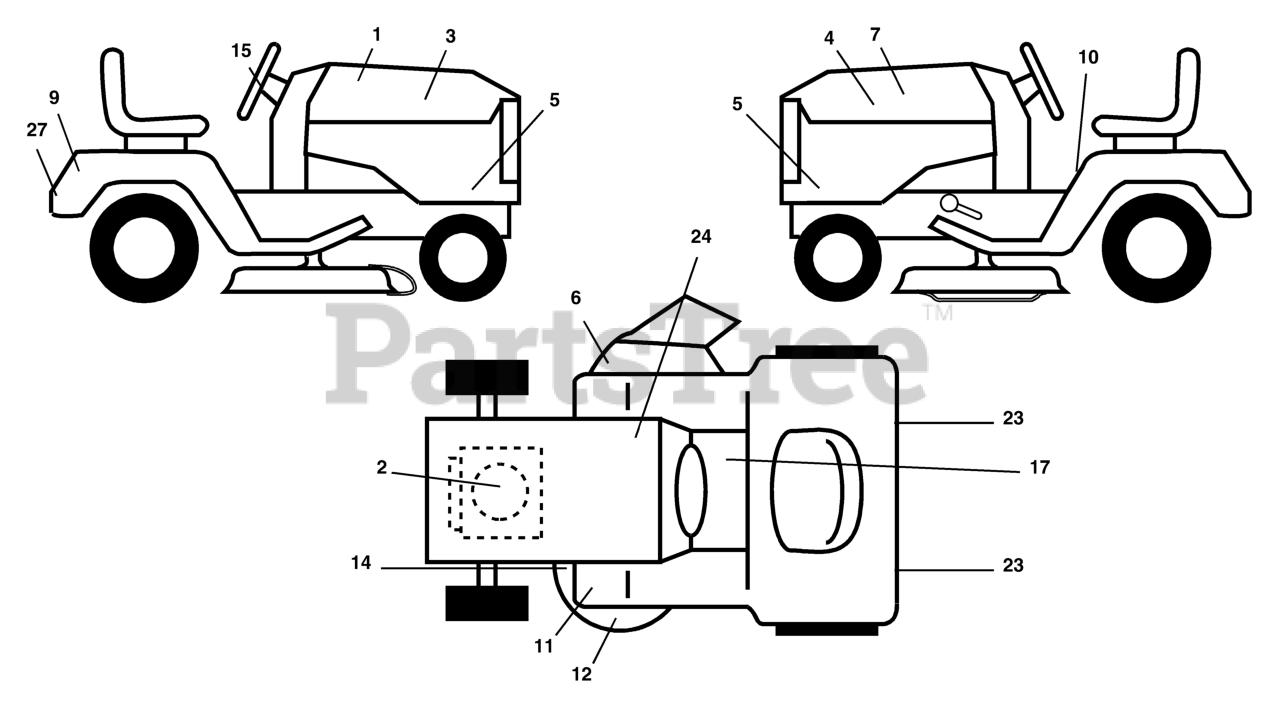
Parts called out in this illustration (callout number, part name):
1	WARNING DECAL
2	DECAL, ENGINE
3	HOOD DECAL LH
4	DECAL, HOOD LH
5	DECAL HOOD SIDES
6	DECAL.WARN.KEEP.HAND.AWAY
7	DECAL HOOD CUST. RESP.
9	DECAL, FENDER
10	DECAL FENDER DANGER
11	DECAL, FOOTREST
12	DECAL CLUTCH/BRAKE
14	DECAL V-BELT SCHEMATIC
15	DECAL.WHEEL.STEERING.HUSQ.PERM
17	DECAL, SADDLE BRAKE PARKING
23	REFLECTOR-TAIL YT
24	DECAL BTRY SYMBOLS
27	DECAL.BYPASS.FENDER.CRD.LT.YT
